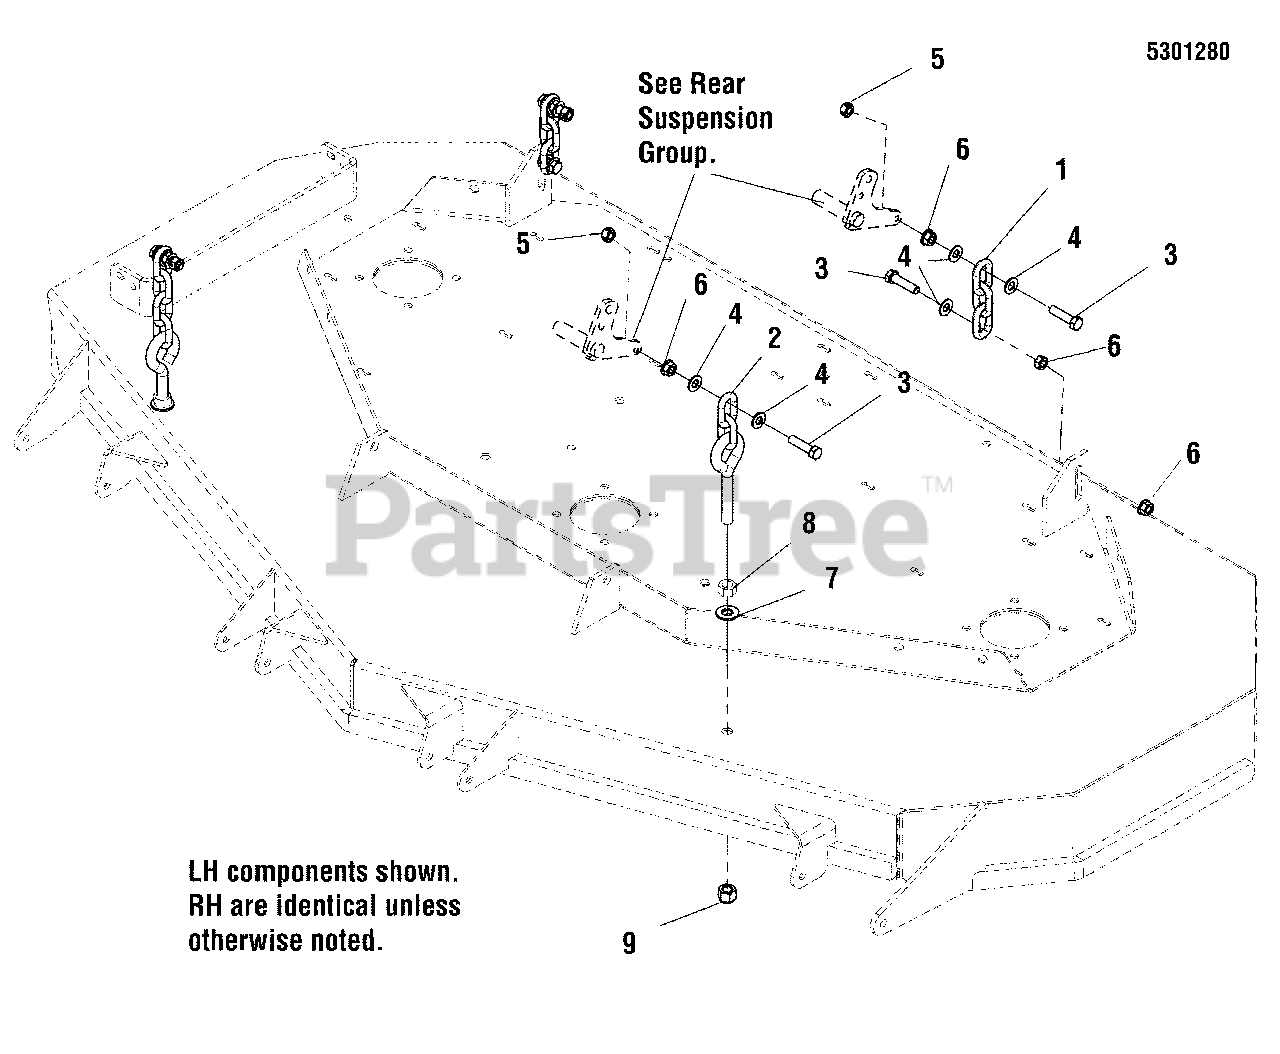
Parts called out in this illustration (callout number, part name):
1	CHAIN, 5/16" GD30, 3 LINKS
2	HANGER, FRONT DECK-2LINK, 5.5" EB
3	BOLT, 3/8-16 X 1-3/4" GD5 CZ
4	WASHER, 3/8 SAE
5	NUT, Hex, Side Lock, 3/8-16
6	NUT, 3/8-16 Hex Large Serrated Flange
7	WASHER, 1/2 SAE
8	NUT, 1/2-13 HEX, YZ
9	NUT, Hex Flange, Nylock, 1/2-13
